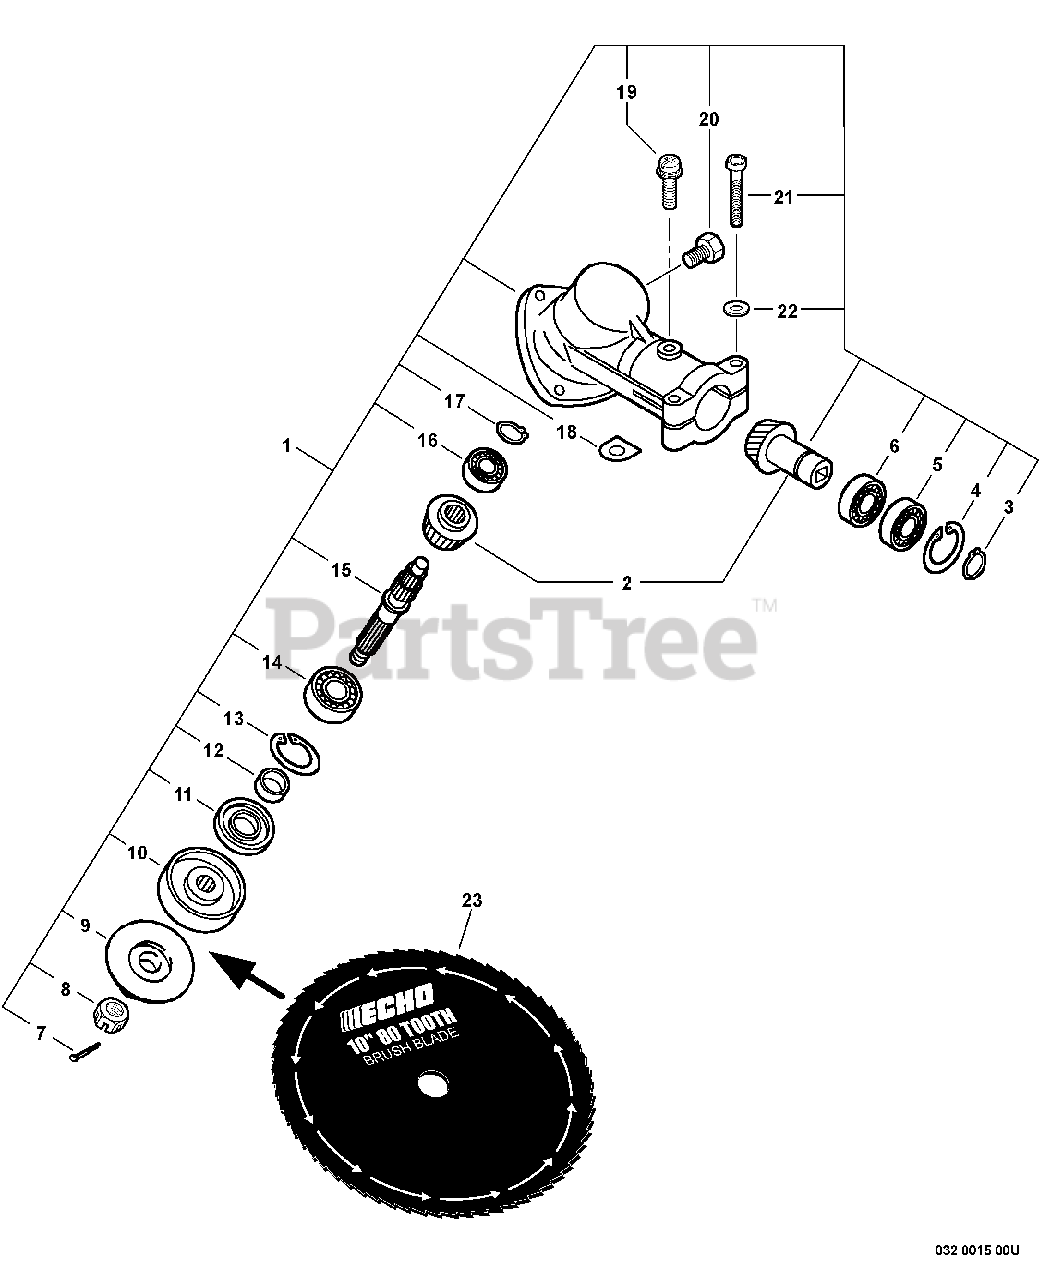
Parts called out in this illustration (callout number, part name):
1	GEAR CASE ASSY
2	GEAR SET - BEVEL
3	RING, RETAINING - 12
4	RING, RETAINING - 28
5	BEARING, BALL - 6001
6	BEARING, BALL - 6001
7	PIN, SPLIT - 2X22
8	NUT - 10 -- LEFT HAND
9	ADAPTOR, BLADE - LOWER
10	ADAPTOR, BLADE - UPPER
11	SEAL, OIL
13	RING, RETAINING - 32
14	BEARING, BALL - 6201
15	GEAR - SHAFT
16	BEARING, BALL - 6000
17	RING, RETAINING - 12
19	SCREW - 5X10
20	BOLT - 8X8
21	BOLT - 5X40
22	WASHER - 5
23	BLADE, 25mm ID - 80 TOOTH -- 10" (25cm)
